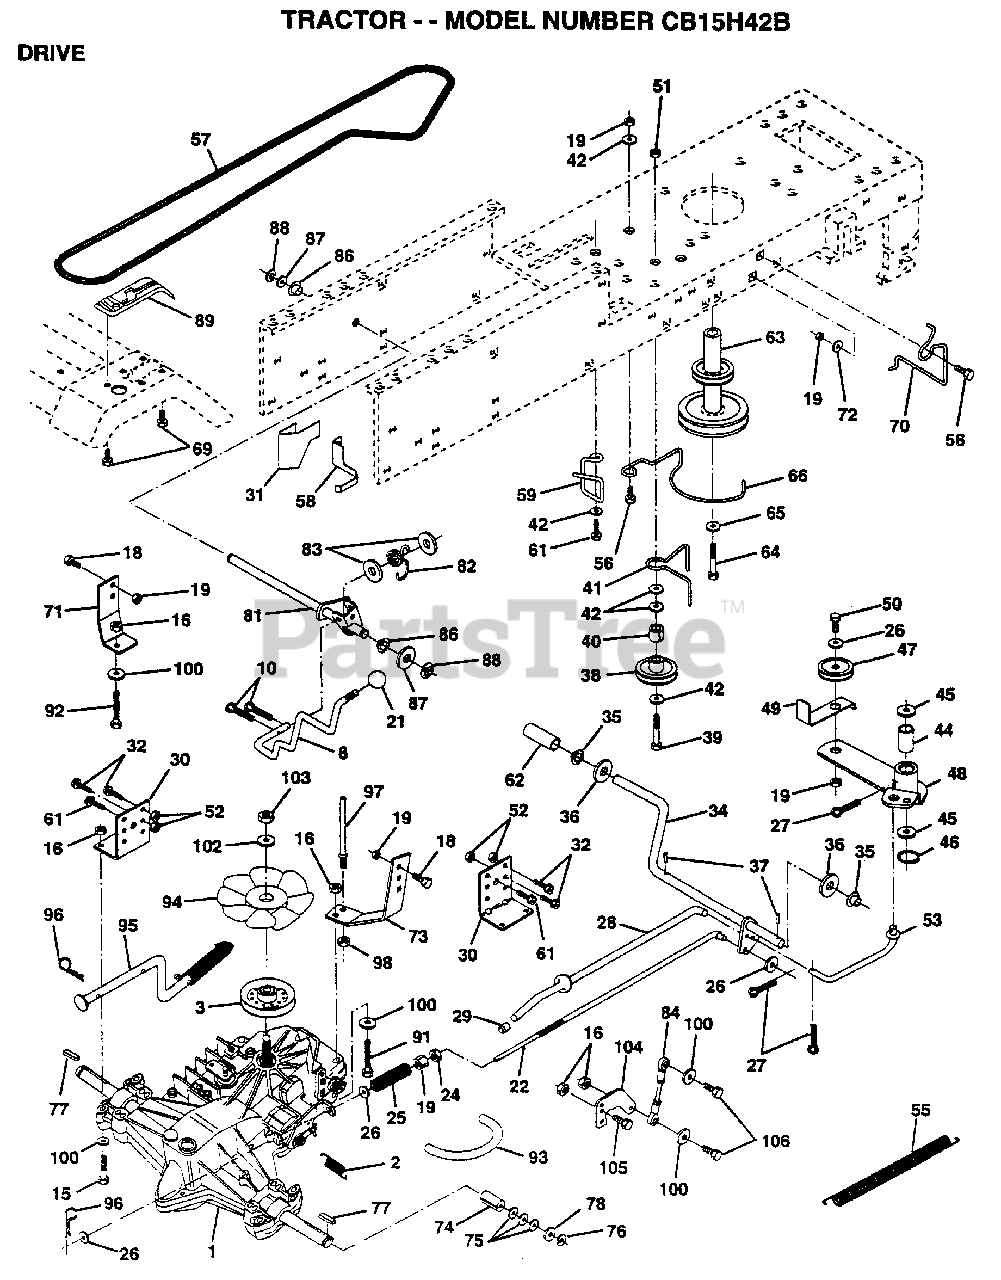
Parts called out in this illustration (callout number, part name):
2	SPRING RET BRAKE
3	PULLEY.TRANSAXLE
4	JAM NUT TI
8	ROD SHIFT FEND LT
10	PIN COTTER 1/8
15	BOLT HEX
16	NUT
18	BOLT
19	NUT
21	KNOB T (1/2-HOLE)
22	ROD.BRAKE.HYDRO.
24	NUT
25	SPRING ROD LT
26	WASHER
27	COTTER PIN
28	ROD.BRAKE.PARK.LT
29	PLUNGER CAP T
30	TRANSAXLE MTG BKT
31	"KEEPER,BELT LH T"
32	BOLT
34	SHAFT.PEDAL.FOOT
35	NYLON BEARING
36	WASHER LT
38	PULLEY.IDLER.FLAT
39	BOLT
40	SPACER T
41	BELT KEEPER LT
42	WASHER
44	"LY, BEARING"
45	WASHER LT
46	KLIP RING
48	ARM IDLER
49	RETAIN BELT
53	"LINK, CLUTCH T"
55	"SPRING, RETURN LT"
57	"BELT.GD DRV 82"""
58	KEEPER BELT LH
59	KEEPER BELT CNTSP
61	SCREW
62	PEDAL COVER T
63	PULLEY.ENGINE
64	BOLT
65	LOCKWASHER
66	KEEPER.BELT.ENG.L
69	SCREW HEXWSH H-L
70	KEEPER BELT ENG
71	STRAP TORQ LH HYD
72	WASHER
73	STRAP TORQ RH HYD
74	SPACER SPLIT
75	WASHER
76	E-RING LT
77	SQUARE KEY
78	WASHER
82	"SPRING,TORSION"
83	WASHER
84	ROD.TIE.BALL.4.75
86	BUSHING
87	WASHER D
88	KLIP RING
92	HEX BOLT
93	"LINE FUEL HYD 4"""
94	"FAN 7"" HYDRO"
96	RETAINER M
97	BOLT KEEPER RH
98	NUT
100	WASHER M
102	WASHER BELLEVILLE
104	ARM CONTROL HYDRO
105	SCREW CAP 5/16-18
106	BOLT
